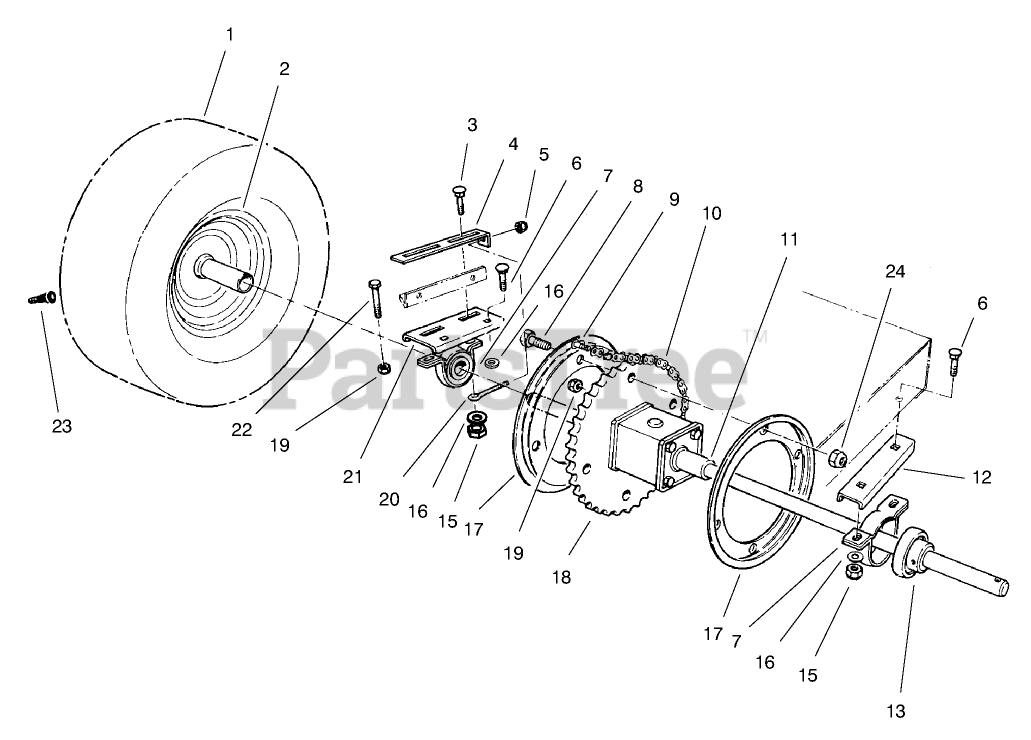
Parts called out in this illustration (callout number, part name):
1	TIRE,PNEU.13X5.00X6
2	WHEEL-REAR
3	SCREW-CARR
4	PLATE-ADJUSTING
5	NUT-LOCK, NI
6	BOLT-CARR
7	RTNR-PILLOW BLK
8	SCREW-HH
9	LINK-CHAIN
10	CHAIN-ROLLER
13	BEARING-BALL
15	NUT-LOCK, NI
16	WASHER-FLAT
17	GUIDE-REAR CHAIN
18	SPROCKET
19	NUT-LOCK, NI
20	SCREW-ADJUSTING
21	RH AXLE SUPPORT
22	AXLE MTG BOLT
24	NUT-HEX
